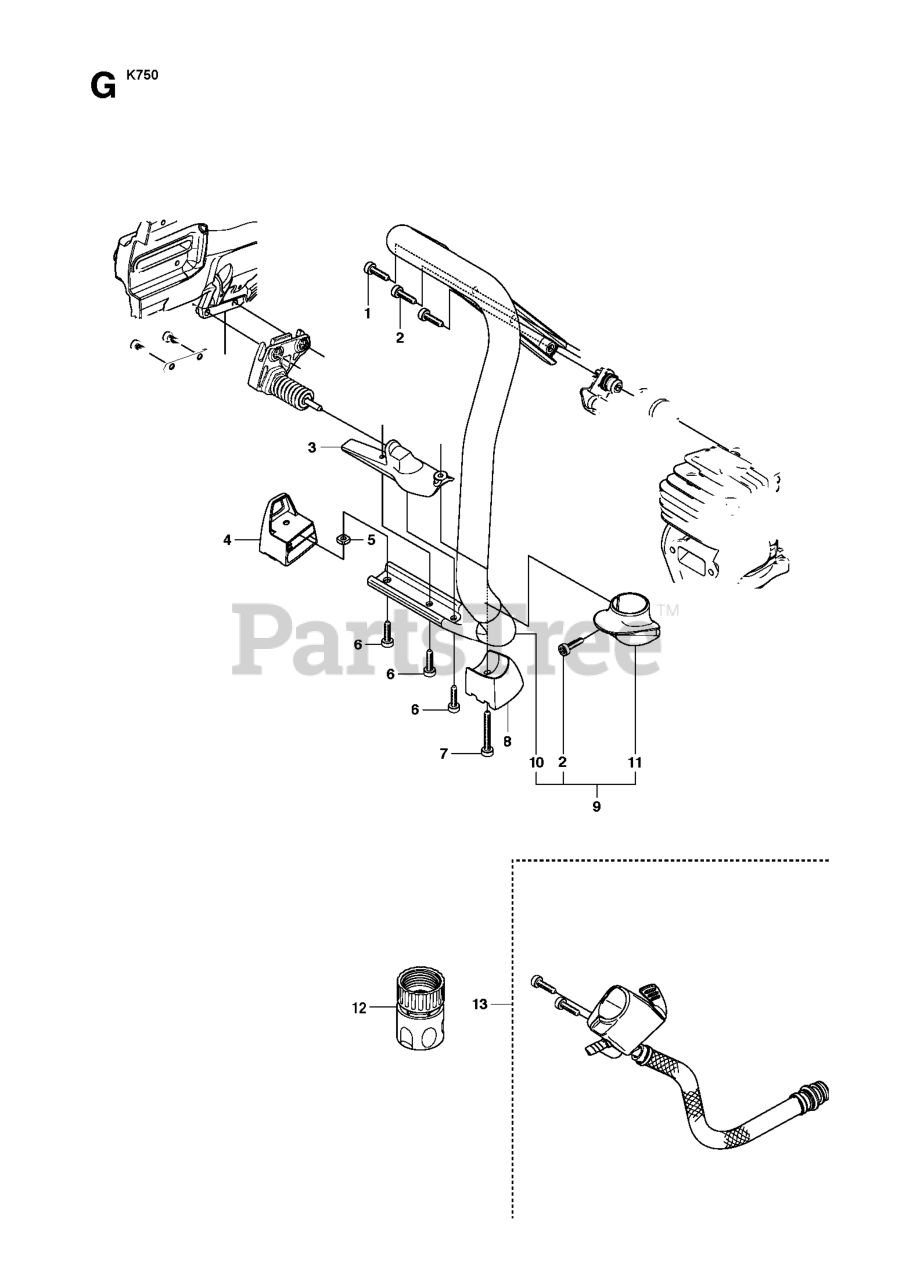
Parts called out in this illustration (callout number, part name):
3	%SPRING RETAINER
4	GROUND SUPPORT
8	GROUND SUPPORT
9	HANDLE FRONT ASSY
10	FRONT HANDLE
12	COUPLER, 1/2" HOSE W/STOP ORIG
12	FEMALE QUICK COUPLER
13	HOSE KIT, WET CUT KIT, HANDLE
